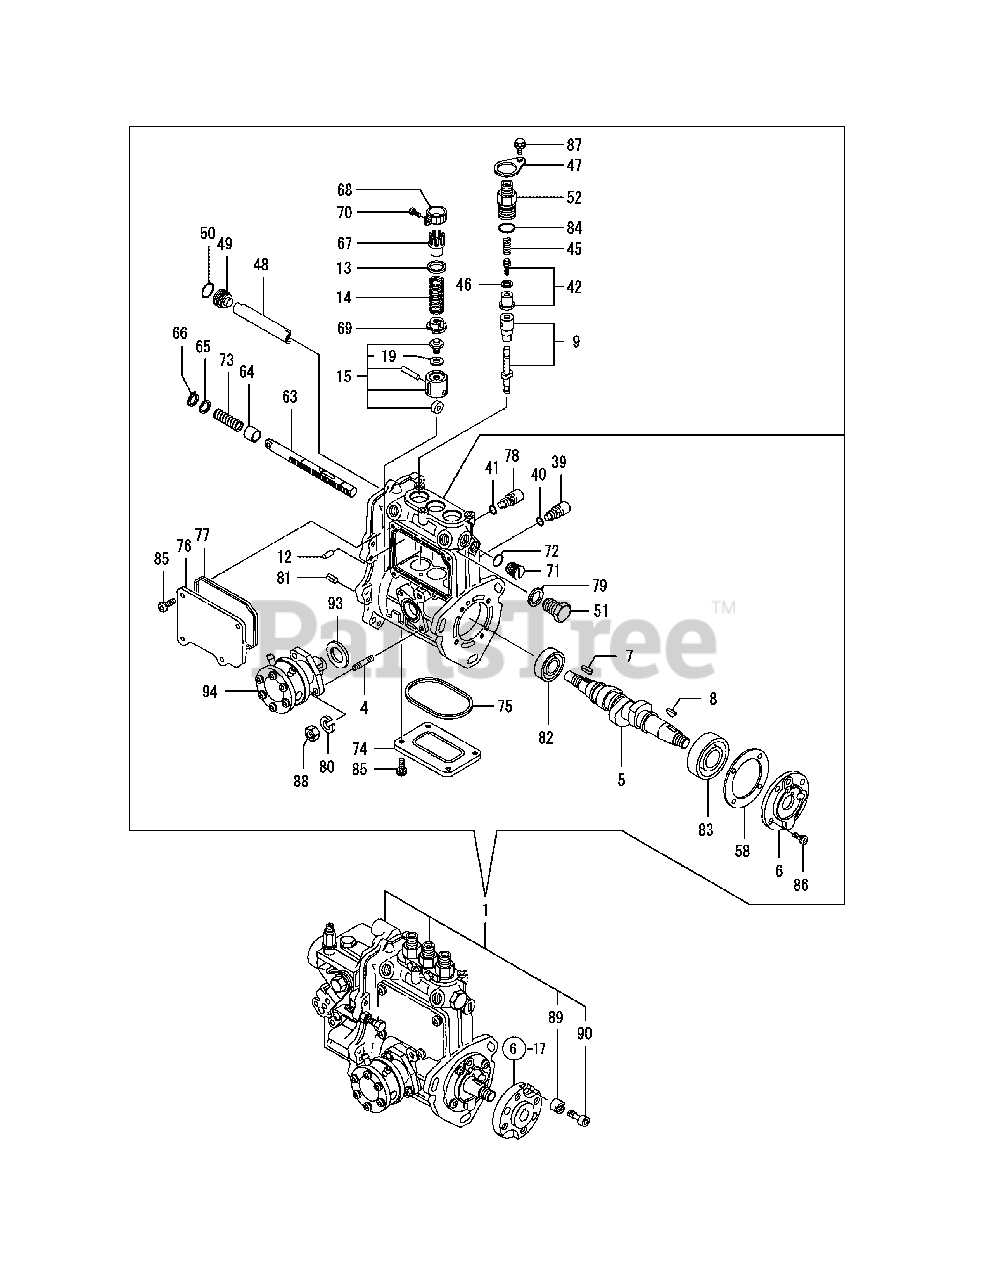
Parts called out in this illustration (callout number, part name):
4	Stud, Feed Pump
6	Support, Bearing
9	Plunger Assembly
12	Pin, Barrel Locking
14	Spring, Plunger
15	Tappet Assembly
42	Valve Assembly, Delivery
45	Spring, Delivery
46	Gasket, Delivery
52	Valve Assembly, Delivery
58	Shim Set, Adjusting
65	Spacer, Aux. Spring
67	Pinion, Control
68	Pinion
69	Receiver, Spring
76	Cover, Body Side
81	Spring Pin, 5 x 10
85	Screw, M 5 x 12
86	Screw, M 6 x 16
87	Bolt, M 5 x 10 Plated
89	Collar, FIC Fix
90	Bolt, Fixation
94	Feed Pump Assembly
